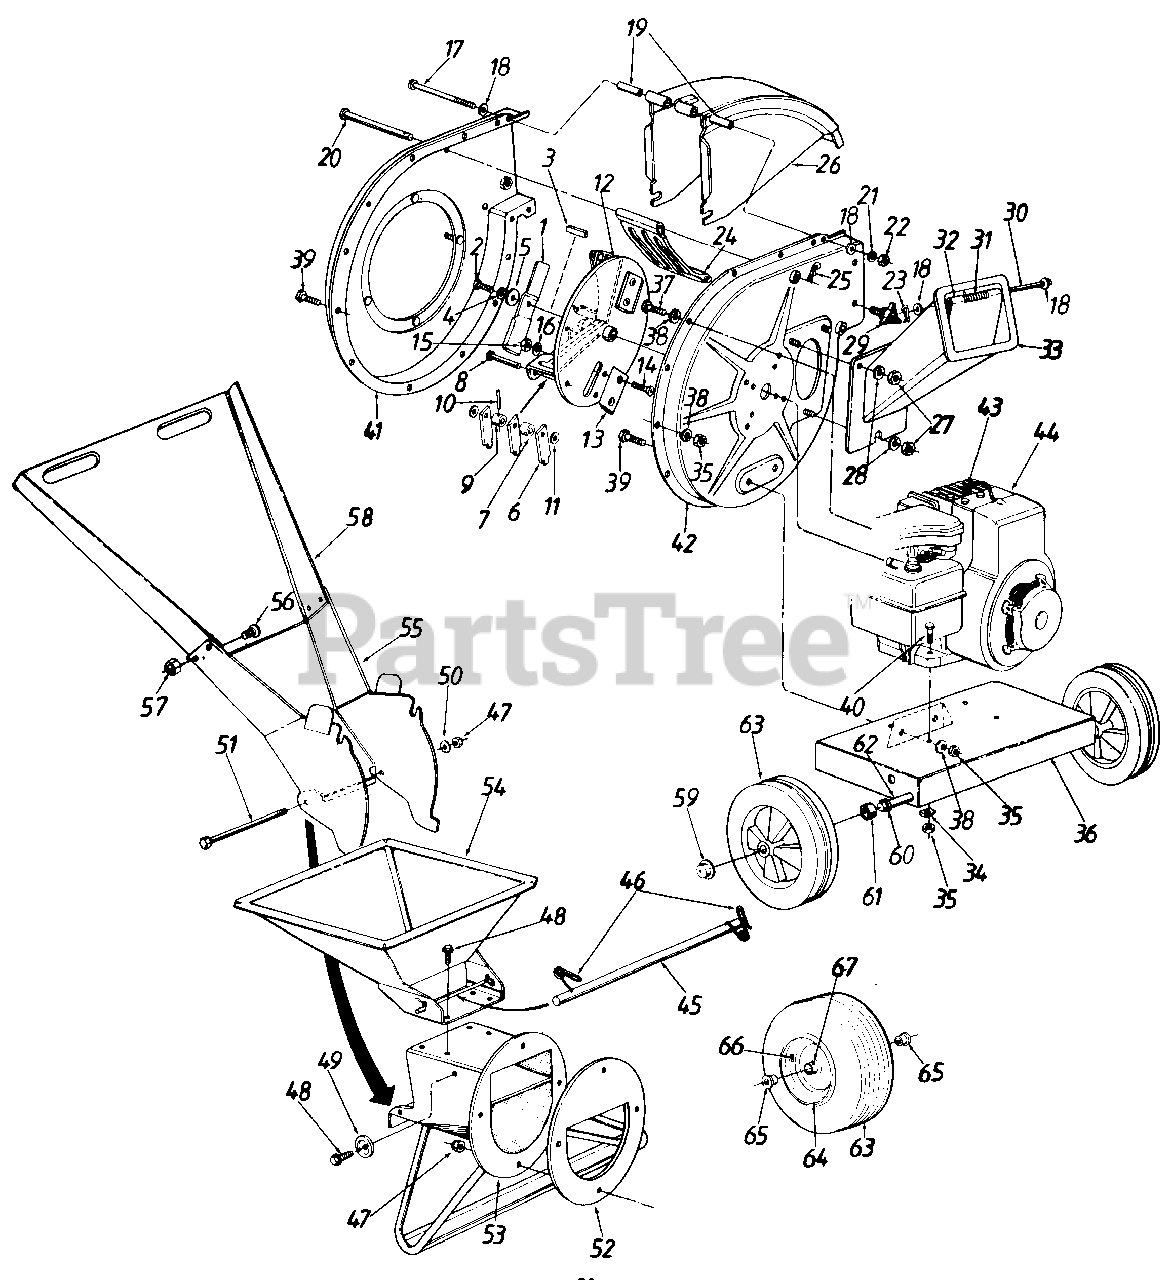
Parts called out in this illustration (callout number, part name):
2	Hex Patch Bolt 3/8-24 x 2" Lg. (Gr. 8)
3	Sq. Key 1/4 x 2.0" Lg.
4	L-Wash. 3/8" I.D. H.D.
5	Fl-Wash. .406" I.D. x 1.25" O.D. Hdn.
6	Flail
7	Flail Spacer
8	Clevis Pin .496" Dia.
9	Flail Spacer w/ 160" Dia. Hole
10	Spring Roll Pin 1.12" Lg.
11	Fl-Wash. .531" I.D. x .94" O.D.
12	Impeller Ass'y.
13	Chipper Blade
14	Flat Hd. Scr. 5/16-24 x .75" Lg.
15	Hex Top L-Nut 5/16-24 (Gr. 5)
16	L-Wash. 5/16" I.D.
17	Hex Bolt 1/4-20 x 4.0" Lg.*
18	Fl-Wash. .344" I.D. x .875" O.D.
19	Chute Hinge Spacer 1.66" Lg.
20	Clevis Pin .5" Dia. x 4.62" Lg.
21	L-Wash. 1/4" I.D.
22	Hex Nut 1/4-20 Thd.*
23	Cap Speed Nut 1/4" Rod
24	Shredder Screen
25	Internal Cotter Pin 3/8" Dia.
27	Hex Nut 5/16-18 Thd. (Gr. 5)
28	Bell-Wash. .345" I.D. x .88"
29	Hand Knob
30	Chipper Door Rod
31	Torsion Spring 1.14" Lg.
35	Hex Nut 5/16-18 Thd. (Gr. 5)
37	Hex Bolt 5/16-24 x .75" Lg.
38	L-Wash. 5116" I.D.*
39	Hex Bolt 5/16-18 x .75" Lg. (Gr. 5)
40	Hex Bolt 5/16-18 x 1.75" Lg.
43	Spark Plug Boot
44	Engine
45	Release Bar
46	Torsion Spring 1.06" Lg.
47	Elastic Lock Nut 5/16-18 Thd.
48	Hex Wash. Hd. Self-Tap Scr. 5/16-18 x .75" Lg.
49	Stop Washer
50	Fl-Wash. 5116" I.D.
51	Hex Bolt 5/16-18 x 8.38" Lg.
52	Back-Up Plate
53	Inlet Guide Ass'y.
57	Hex L-Nut 1/4-20 Thd.
60	Fl-Wash. .64" I.D. x 1.24"
61	Spacer .64" I.D. x .38" Lg.
62	Shredder Axle (645)
62	Shredder Axle (648)
63	Wheel Ass'y. Comp. (645)
63	Wheel Ass'y. Comp. (648)
63	Tire Only (648)
64	Rim Only (648)
65	Flange bearing .632" I.D. (648)
66	Air Valve (648)
67	Grease Fitting (648)
